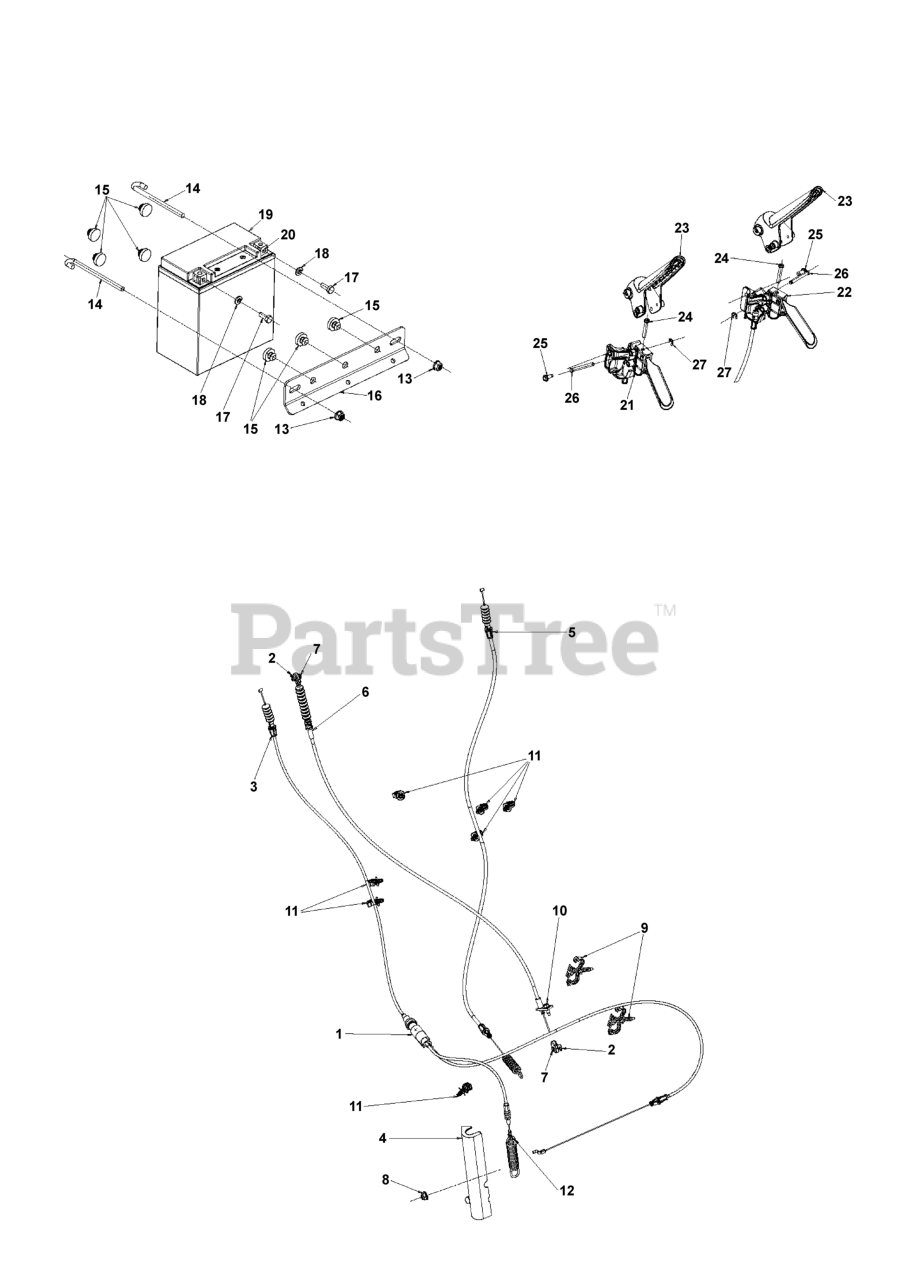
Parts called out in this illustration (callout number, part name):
1	CLIP.CABLE.BLK
2	HAIRPIN.SOFT.ZINC.059X1.125
3	CABLE IMPELLER
4	COVER AUGER CABLE
5	CABLE ASSY DRIVE
6	CABLE HYDRO SPEED
7	PIN CLEVIS .25 X ..4375
8	NUT HEXAGON FLANGE 5/16-18 ST
9	CLIP.CONDUIT.DOUBLE LOOP
10	HEX.WASHER.HEAD 1/4-20 X .65
11	CABLE, 1/4 BLACK FIR TREE
12	SPRING EXTENSION; AUGER EXTENS
13	NUT FLG, NYLOCK, 1/4-20 GR G C
14	HOOK.J.BATTERY
15	GROMMET.BUMPER
18	WASHER 1/4 INT TOOTH
24	SCREW HEX_WASH_13-16 X 1.50_H
25	SCREW 14-20 X 5/8
26	PIN.GROOVED
